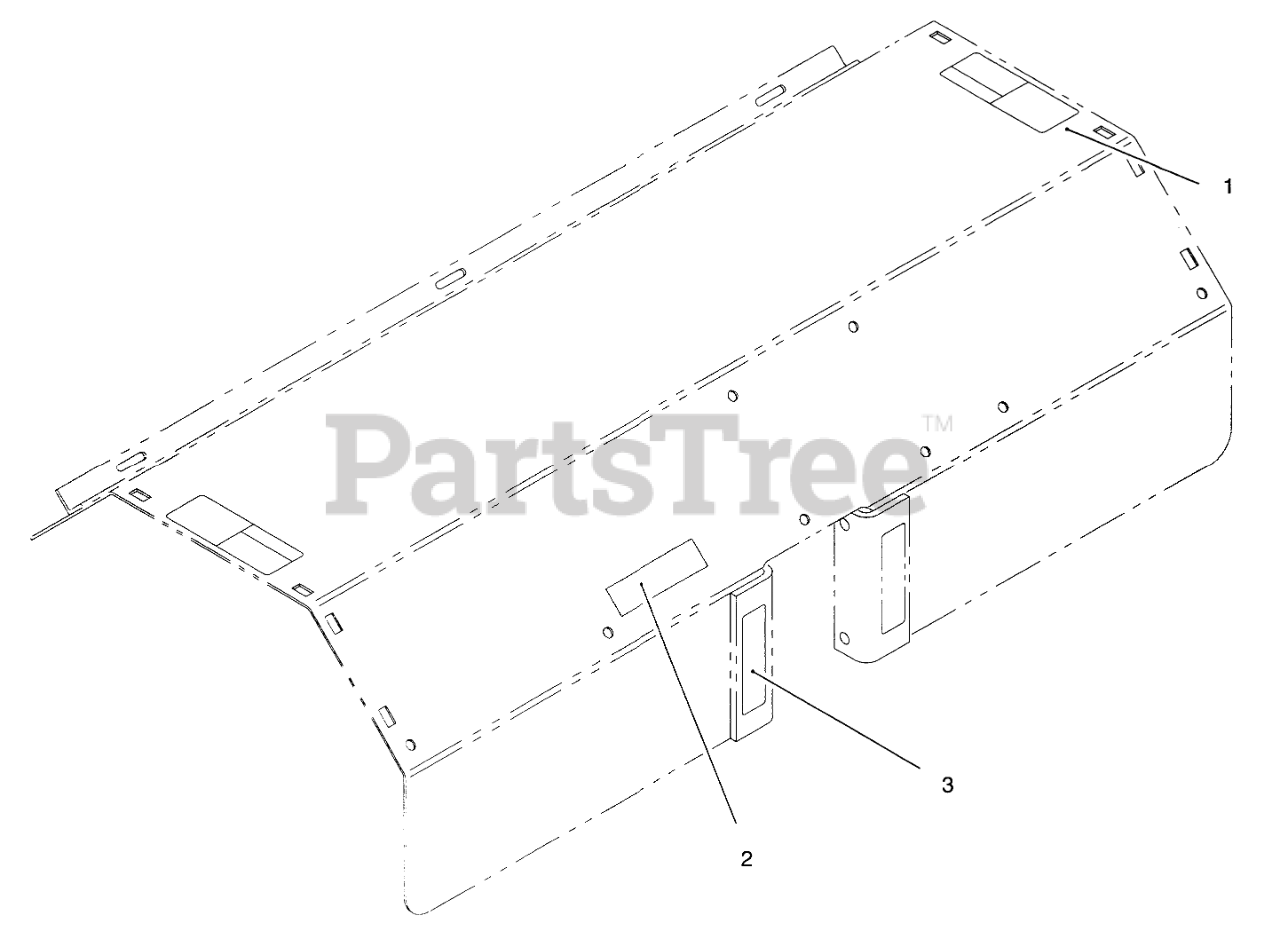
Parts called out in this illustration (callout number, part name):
1	DECAL-DANGER
2	DECAL - BELT ROUTING
3	Decal CE
